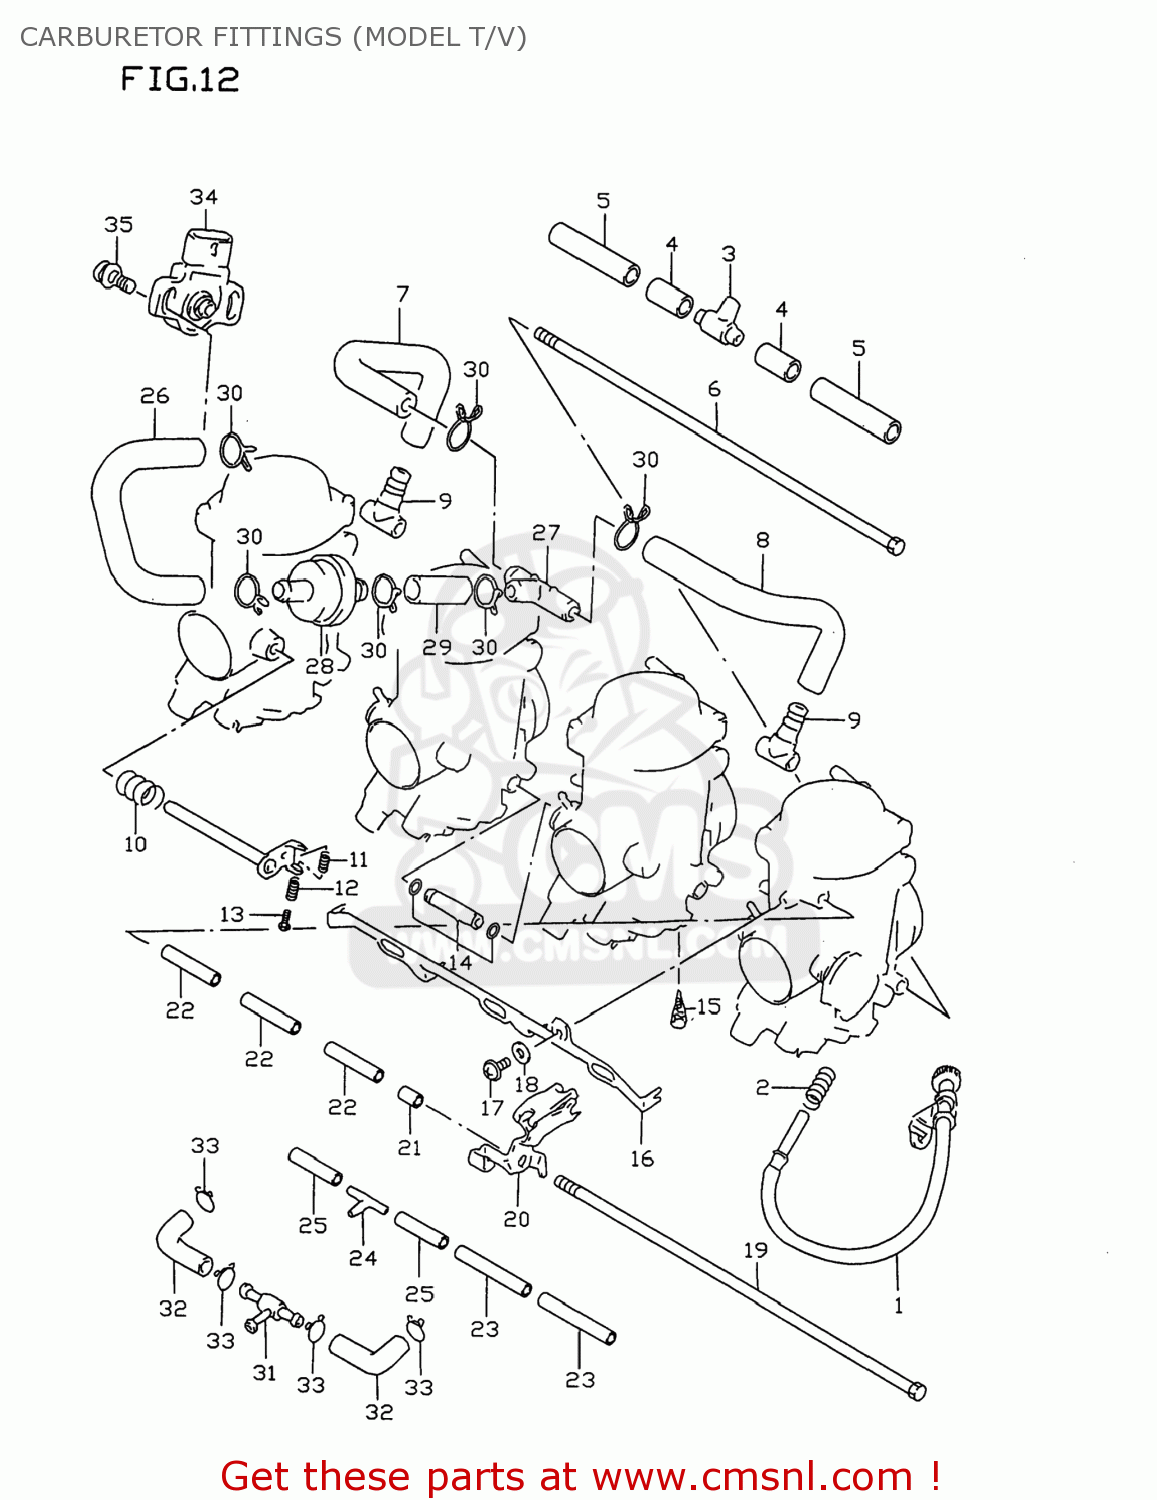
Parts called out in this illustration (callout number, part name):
1	ADJUSTER
2	SPRING
3	NIPPLE
4	HOSE
5	HOSE
6	BOLT
7	HOSE
8	HOSE
9	3 WAY
10	SPRING
11	SPRING,THROTTLE SCREW
12	SPRING
13	SCREW
14	NIPPLE,CARBURETOR
15	FILTER
16	LEVER,STARTER
17	SCREW
18	PACKING
19	BOLT
20	BRACKET
21	RING
22	PIPE
23	HOSE
24	3-WAY
25	HOSE
26	HOSE,AIR VENT(NO.1)
27	JOINT
28	FILTER,AIR VENT
29	HOSE(11X15X600)
30	CLIP
31	NIPPLE
32	HOSE
33	CLIP
34	SENSOR ASSY,THROTTLE
35	SCREW, SENSOR
